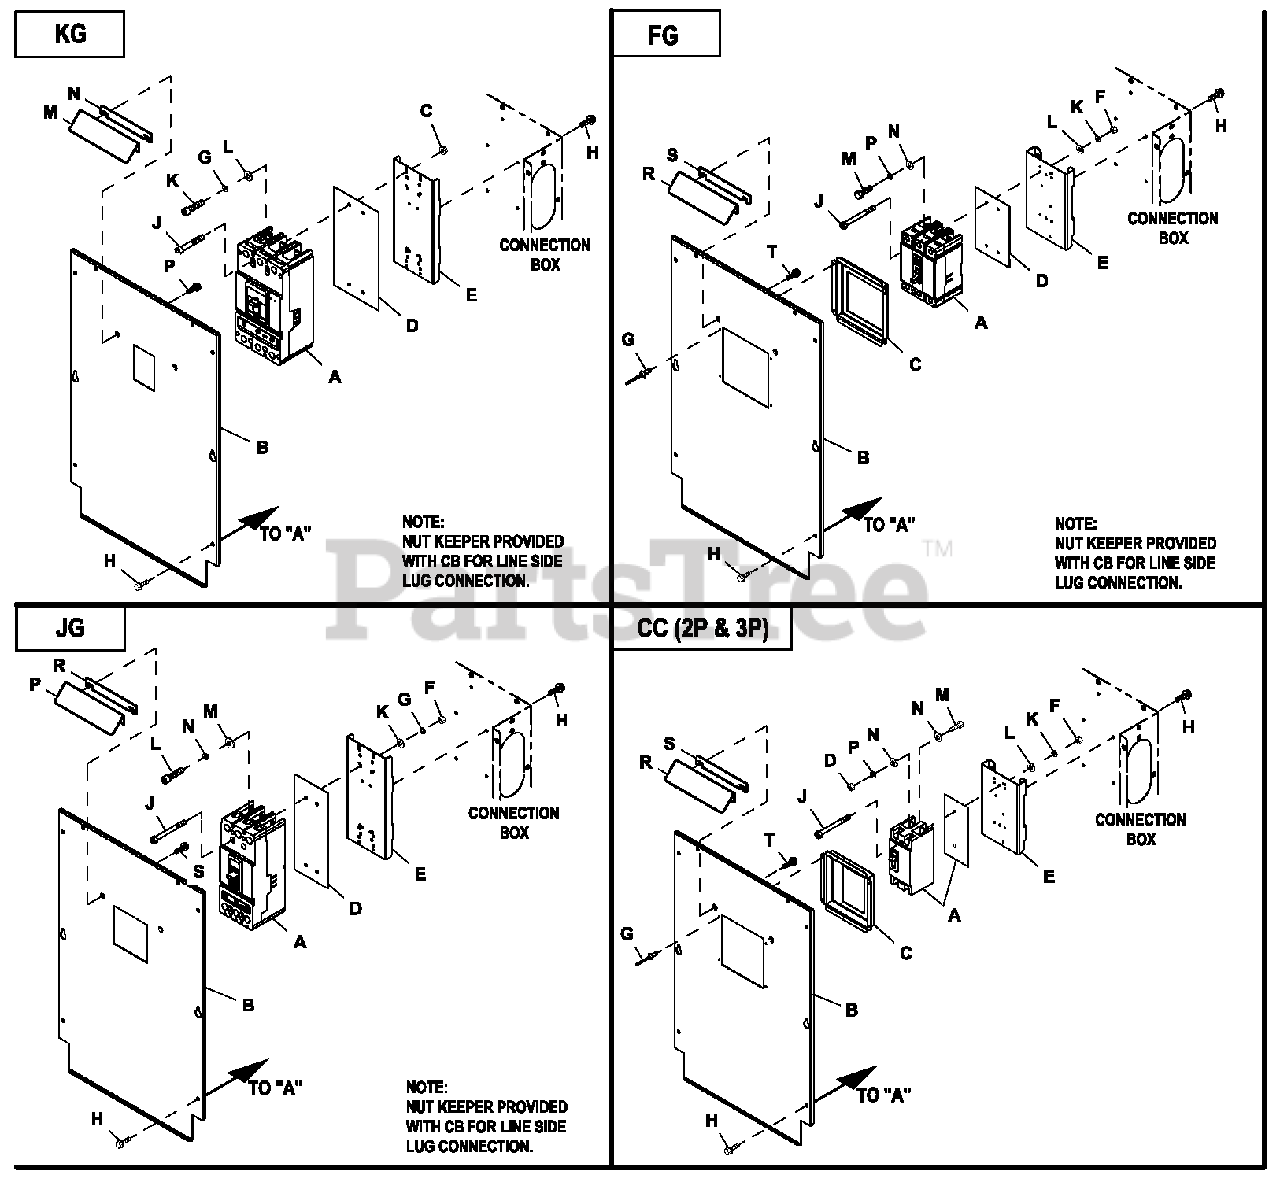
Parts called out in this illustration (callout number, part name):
A	ROTOR-2390-35KD1 CPL
B	ROTOR-2390-45KD1 CPL (G2)
C	ROTOR-2390-35KD1 CPL (G2)
D	ROTOR 25KW 3PH DIRECT 390 1800
E	ROTOR 25KW 1PH DIRECT 390 1800
G	WASHER LOCK M8-5/16
H	SCREW HWHT M 6-1 X 16 N WA Z/JS
J	SCREW SHC M 6-1.0 X 50 C8.8
K	STATOR-390 45K 2P 1PH DIRECT
L	STATOR-2390-35AD1 CPL
M	STATOR-2390-35KD1 CPL
N	STATOR-2390-35GD1 CPL
P	STATOR-2309-45KW 2P 3PH 208V
A	CB 0060 3P 480V E FG LL
B	COVER CB C2 CPL
C	COVER CB DISH 3P E FG
D	INSULATOR CB 3P E TYPE CC/FG
E	STANDOFF CB BOX CONBOX
F	NUT HEX #8-32 STEEL
G	RIVET POP .125 X .275 SS
J	SCREW PPHM #8-32 X 1-3/4 ZINC
K	WASHER LOCK #8- M 4
L	WASHER FLAT #8 ZINC
M	SCREW HHC M 5-0.8 X 20 G8.8
N	WASHER FLAT #10 ZINC
P	WASHER LOCK M5
R	SHIELD-S M CIRCUIT BREAKER
S	GASKET-CB SHIELD C2
T	SCREW HWHTF M 6-1.0X16
A	CB 0250 3P 600V E JG LL
B	COVER CB E JG C2 CONBOX
D	INSULATOR CB E 3P JG
E	STANDOFF CB MOUNT CONBOX
F	NUT HEX 1/4-20 STEEL
G	WASHER LOCK M 6-1/4
J	SCREW RHM 1/4-20X3
K	WASHER FLAT 1/4-M6 ZINC
L	SCREW SHC M8-1.25 X 20 G8
M	WASHER FLAT 5/16- M8 ZINC
N	WASHER LOCK M8-5/16
P	SHIELD-S M CIRCUIT BREAKER
R	GASKET-CB SHIELD C2
S	SCREW HWHTF M 6-1.0X16
A	CB0175A2P 240VECCLL
C	COVER CB DISH 2P E CC
D	N UT HEX M5-0.8 G8 CLEAR ZIN C
E	STA N DOFF CB BOX CO N BOX
F	N UT HEX #8-32 STEEL
H	SCREW HWHT M6-1 X 16 N WA Z/JS
J	SCREW RHM #8-32X3-1/4
K	WASHER LOCK#8-M4
L	WASHER FLAT #8 ZIN C
M	SCREW HHC M5-0.8 X 20 G8.8
N	WASHER FLAT #10 ZI N C
R	SHIELD-SM CIRCUIT BREAKER
T	SCREW HWHTF M6-1.0X16
